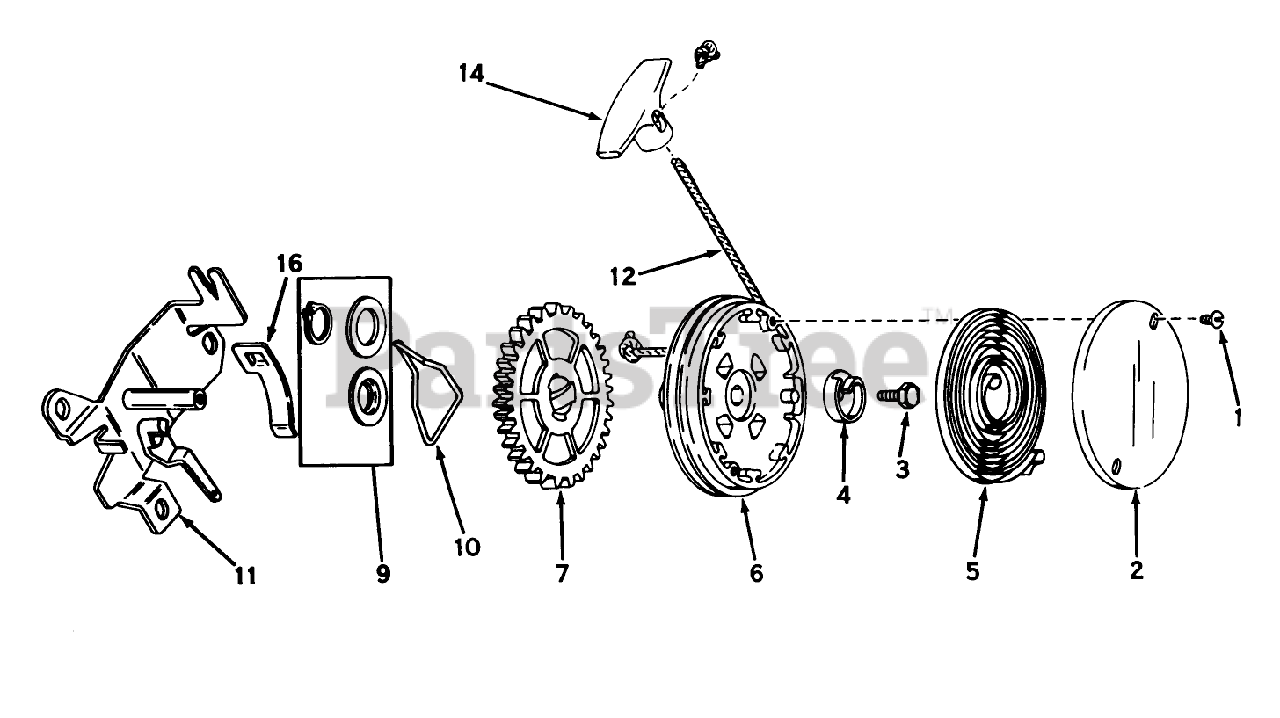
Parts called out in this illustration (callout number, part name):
1	Screw
2	Cover, Spring
3	Screw, Hex Washer Head
4	Hub Spring
5	Spring, Rewind
6	Pulley Assy. (Incl. No. 9)
9	Kit, Thrust Wash. Snap Rg.
10	Brake
11	Bracket Assy., Mounting
12	Rope-Starter
14	Handle-Starter
16	Clip Rope
